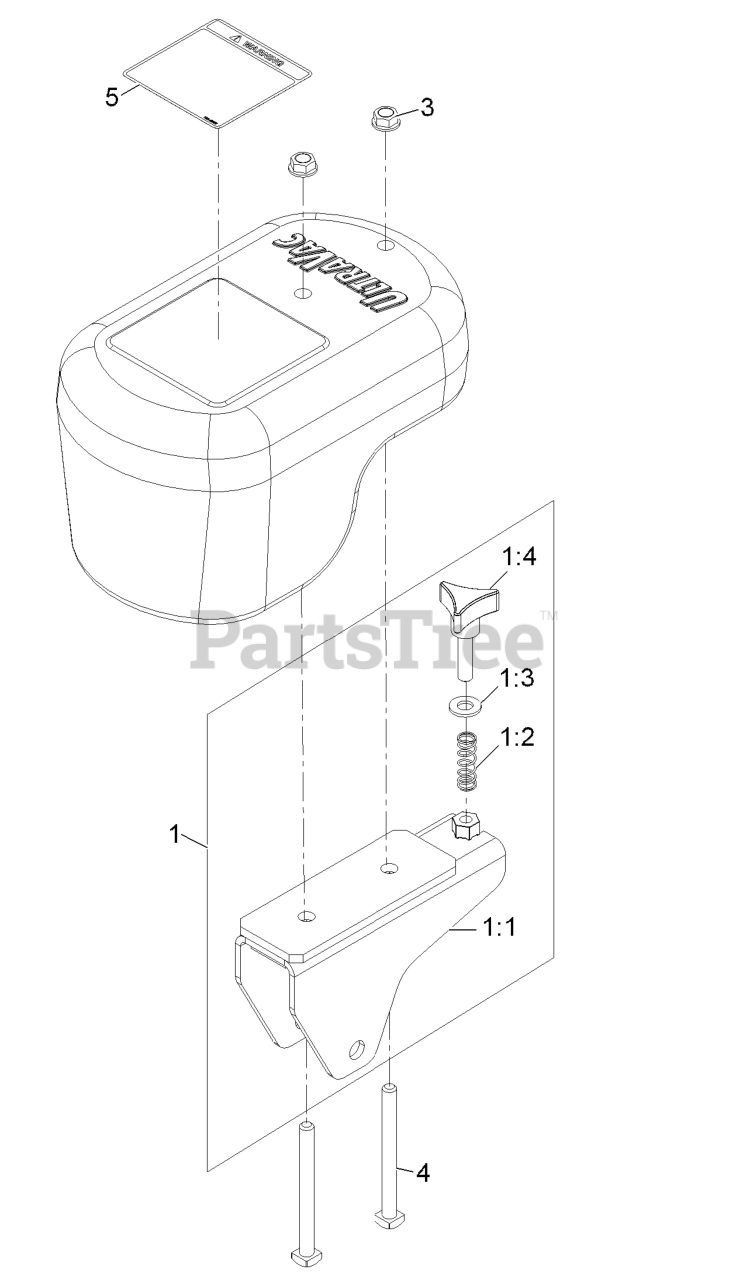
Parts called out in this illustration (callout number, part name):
1	ASM,CASTER WEIGHT BRACKET
1:1	WLD,CASTER WEIGHT BRACKET
1:3	WASHER-FLAT
3	NUT-HHF, WHIZ
4	BOLT, SQUARE HEAD YZ
5	DECAL,WEIGHT
